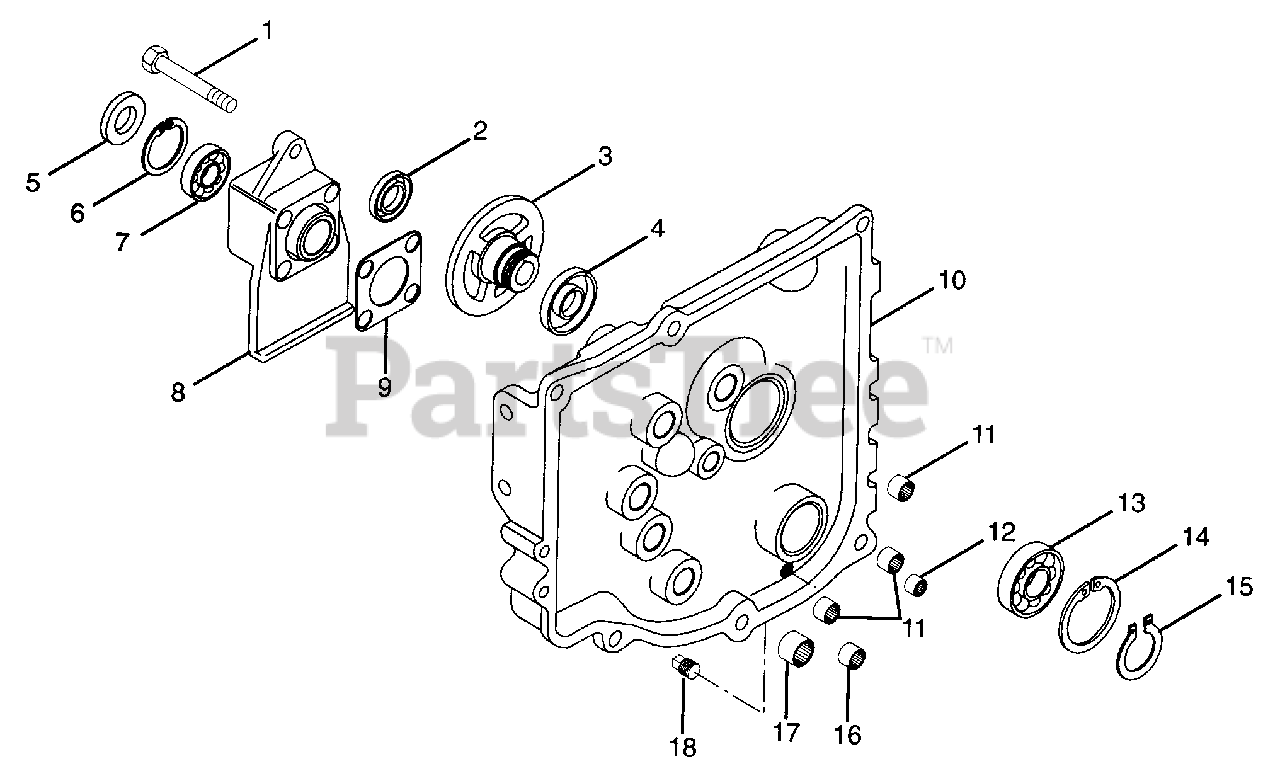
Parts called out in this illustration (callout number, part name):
1	Bolt-Hex .50-13 x 3.25 Grade 5
2	Seal .750 x 1.625 x .250
3	Hub-Clutch
4	Seal-Lip 2.25 x 3.25 x .38
5	Seal 1.250 x 2.250 x .500
6	Ring-Retaining-External 2.49 x .078
7	Bearing-Ball 1.25 x 2.25 x .50
8	Axle Bearing Retainer
9	Gasket
10	Assembly-Transmission Cover
11	Bearing-Needle .75 x 1.0 x .75
12	Bearing-Needle .625 x .812 x .75
13	Bearing-Ball 1.97 x 3.54 x .79
14	Ring-Retaining-Internal 3.54 x .109
15	Ring-Retaining-External 1.819 x .062
16	Bearing-Needle .75 x 1.0 x .75
17	Bearing-Needle 1.0 x 1.25 x .75
18	Plug-Pipe .38
